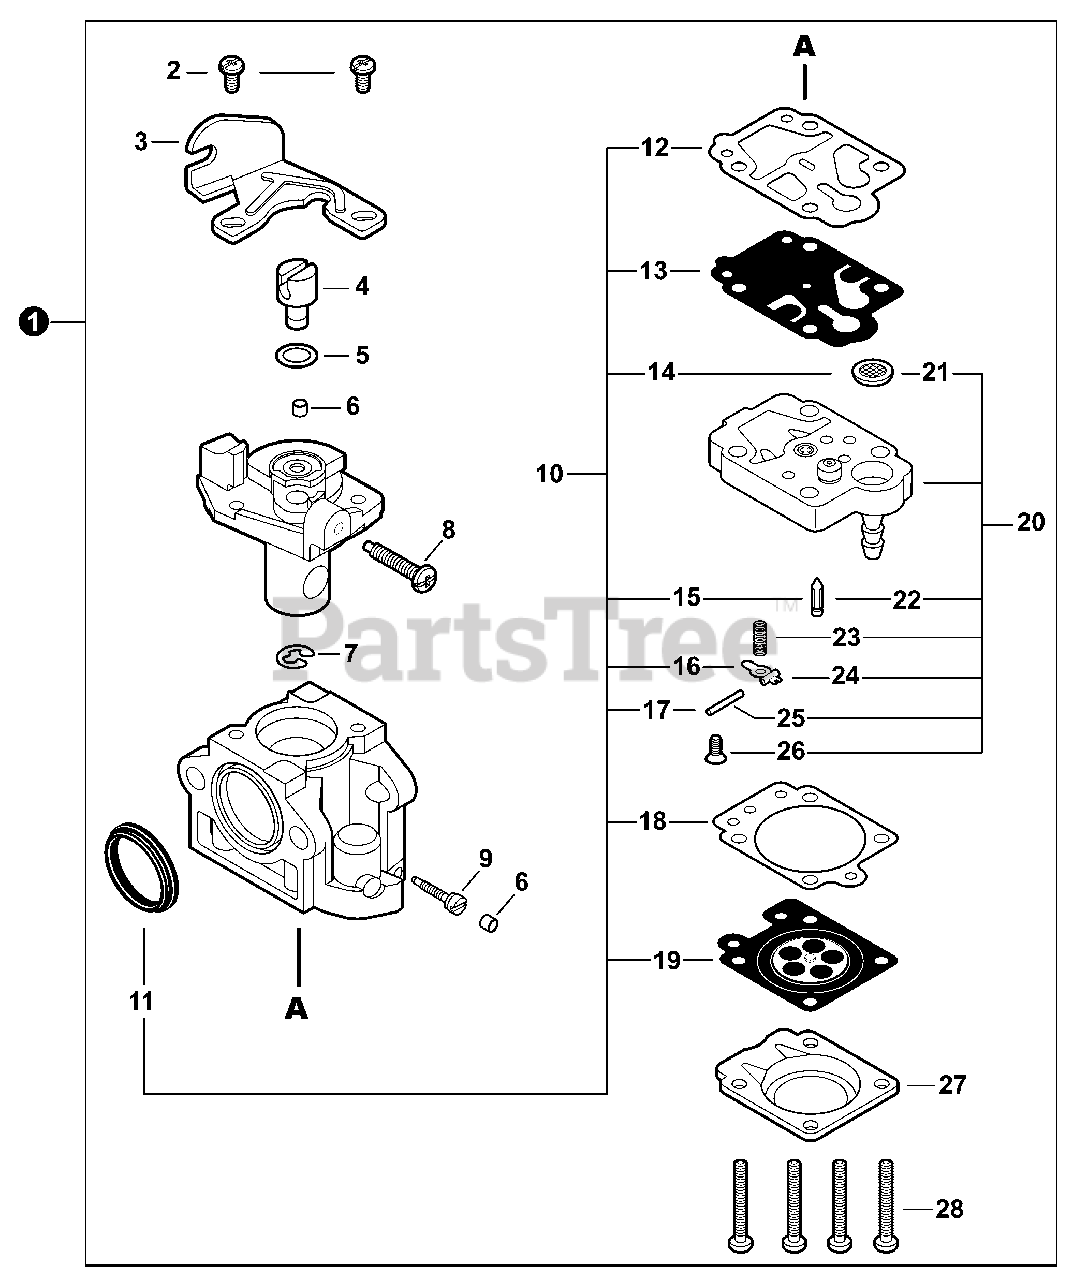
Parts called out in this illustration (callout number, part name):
1	CARBURETOR - WYK-226A
3	BRACKET, THROTTLE CABLE
6	CAP, LIMITER
9	NEEDLE, HIGH SPEED
10	REPAIR KIT, CARBURETOR
11	RING, PACKING
12	GASKET, PUMP
13	DIAPHRAGM, PUMP
14	SCREEN, FUEL INLET
15	VALVE, INLET NEEDLE
16	LEVER, METERING
17	PIN, METERING LEVER
18	GASKET, METERING DIAPHRAGM
19	DIAPHRAGM, METERING
20	BODY ASSY, PUMP
21	SCREEN, FUEL INLET
22	VALVE, INLET NEEDLE
23	SPRING, METERING LEVER
24	LEVER, METERING
25	PIN, METERING LEVER
26	SCREW
27	COVER, PUMP
